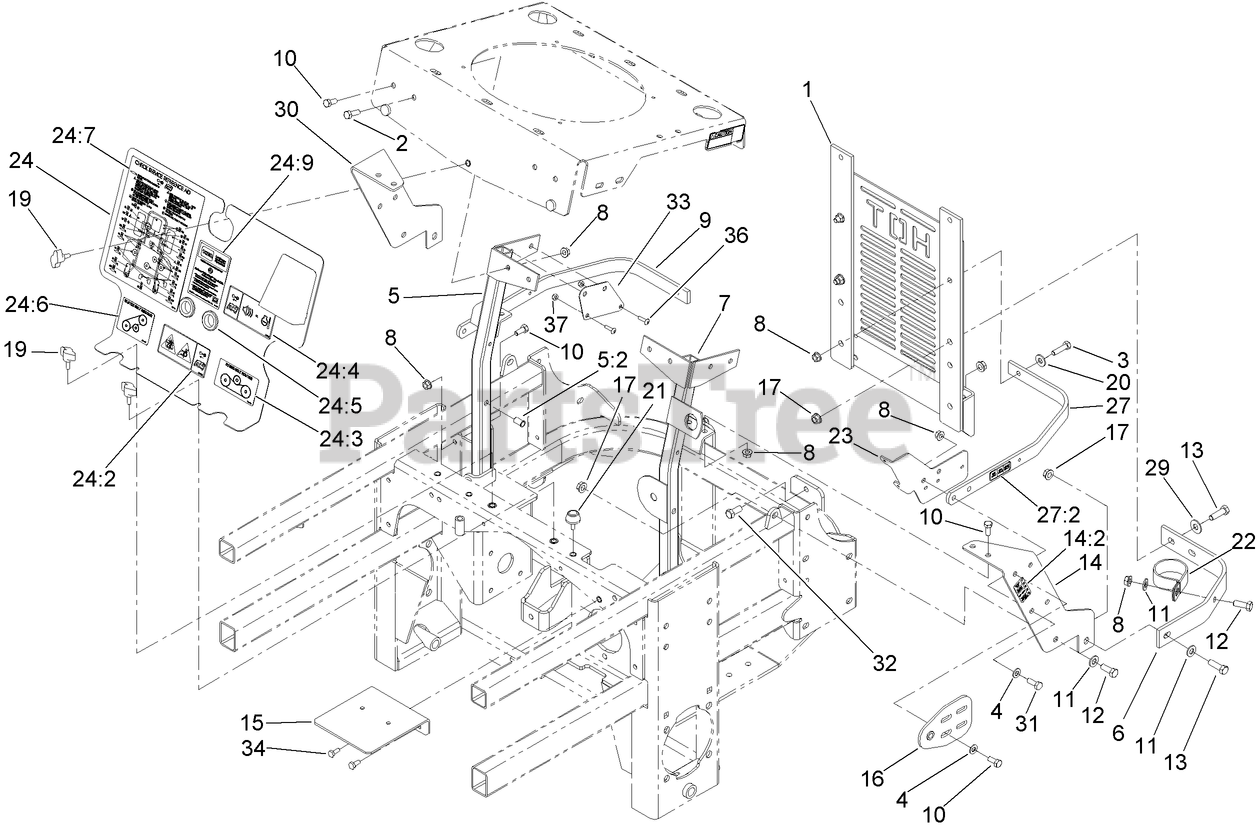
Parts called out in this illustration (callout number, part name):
1	REAR GUARD ASM
2	SCREW-HH
3	SCREW-HH
4	WASHER-PLAIN
5	RH RADIATOR BRACE ASM
5:2	INSERT-THREADED
6	STRAP-GUARD
7	LH RADIATOR BRACE ASM
8	NUT-HF
10	SCREW-HH
11	WASHER-FLAT
12	SCREW-HH
13	SCREW-HH
14	BRACKET-SUPPORT, LH
14:2	DECAL-FUSE
15	BRACKET-MOUNT, PUMP
16	PLATE-PIVOT, HOOD
17	NUT-HHF, WHIZ
20	WASHER-FLAT
21	BUMPER-RUBBER
22	CLAMP-R
23	BRACKET-RELAY/FUSE
24	FRONT SHIELD ASM
24:2	DECAL-DANGER, ROTATING DEVICES
24:3	DECAL-ROUTING, HYDRO BELT
24:4	DECAL- WARNING, BUZZER
24:5	GROMMET-RUBBER
24:6	DECAL-ROUTING, CLUTCH BELT
24:7	DECAL-CHECK, SERVICE
24:9	DECAL-COOLANT
27	STRAP-TOP W/DECAL
27:2	DECAL-RELAY
29	WASHER-FLAT
30	BRACKET-SUPPORT, RH
31	SCREW-HH
32	SCREW-HH
33	PLATE-ECM MOUNT
34	SCREW-HH
36	SCREW-HEAD, TRUSS
37	NUT-LOCK, NI
